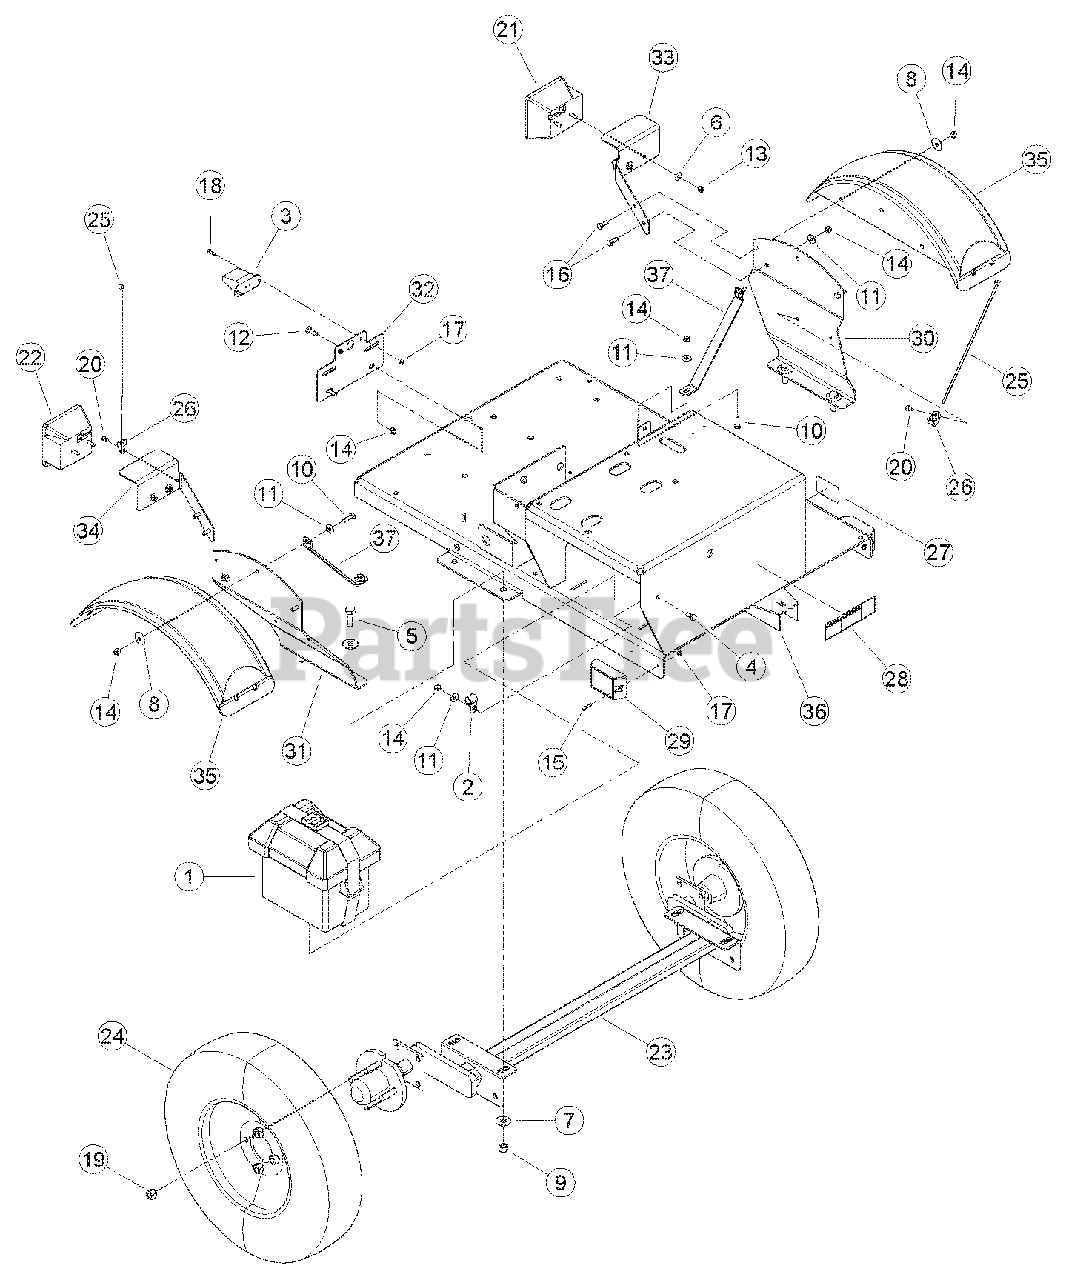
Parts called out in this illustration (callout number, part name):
1	BOX, SMALL BATTERY
2	CLAMP, 9/16 COATED
3	LIGHT, LICENSE PLATE
4	BOLT, 5/16 X 3/4 HEX GR5 ZP
5	BOLT, 1/2 X 1-1/2 HEX HD GR5 ZP
6	WASHER, 1/4 FLAT ZP
7	WASHER, 1/2 FLAT ZP
8	WASHER, 5/16 FENDER ZP
9	NUT, 1/2 CENTERLOCK GRB ZP
10	BOLT, 5/16 X 1 HEX HD GR5 NC ZP
11	WASHER, 5/16 FLAT ZP
12	BOLT, 5/16 X 1 CRG GR5 ZP
13	NUT, 1/4 NE NYLOCK ZP
14	NUT, 5/16 NE NYLOCK ZP
15	MACH. SCREW, 10-24 X 1 RND HD PHL ZP
16	BOLT, 5/16 X 7/8 HEX HD GR5 NC ZP
17	NUT, 10/24 NYLOCK TYPE NM, ZP
18	MACH. SCREW, #10-24 X 3/4 PAN HD PH ZP
19	NUT, 1/2-20 WHEEL
20	RIVET, AL BLIND 1/4 X 3/4 DOME HEAD
21	LIGHT, LH TAIL
22	LIGHT, RH TAIL
23	AXLE, 1000LB TORSION
24	ASSEMBLY, 5.30-12 TIRE + SPOKE RIM
25	STRAP, 11 IN. BLACK TIE
26	CLAMP, CABLE MOUNT
27	DECAL, 5.30-12 LOAD RATING
28	DECAL, CHECK WHEELS
29	LIGHT, AMBER SIDE MARKER
30	BRACKET, LH FENDER
31	BRACKET, RH FENDER
32	PLATE, LICENSE
33	BRACKET, LIGHT LH
34	BRACKET, LIGHT RH
35	FENDER, BLACK PLASTIC DRILLED
36	WELDMENT, C/S TRAILER
37	BRACE, FENDER
